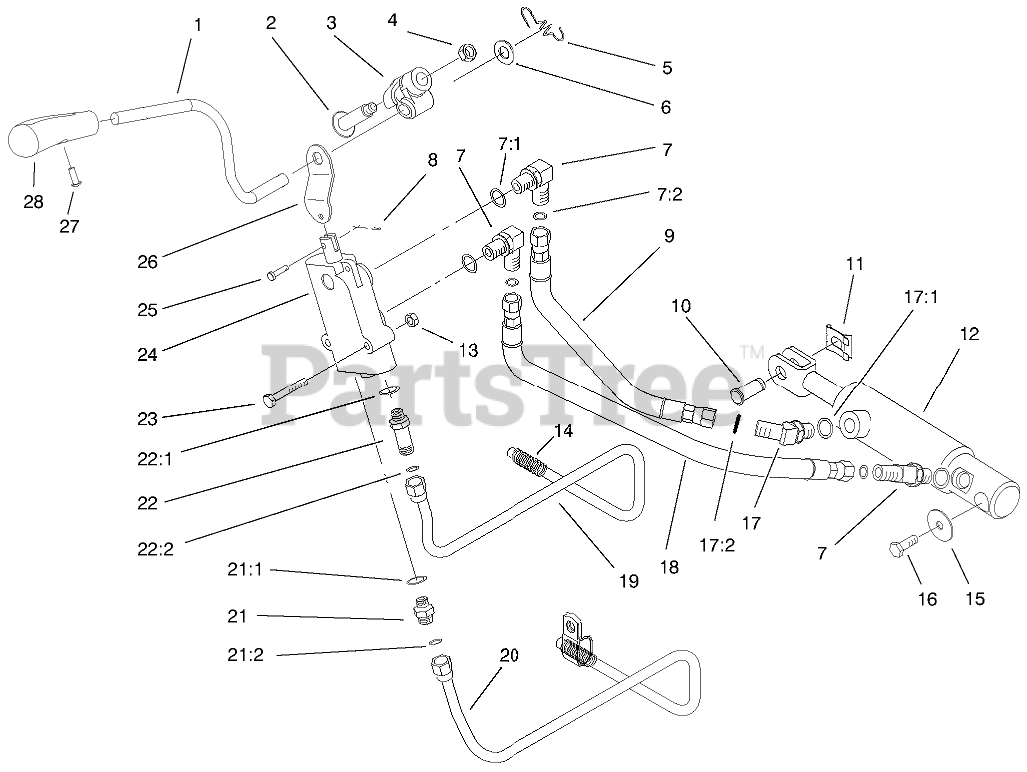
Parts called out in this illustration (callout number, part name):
1	HANDLE-LIFT
2	BOLT-SHOULDER
3	TRUNNION-LEVER, LIFT
4	NUT-JAM, LOCKING
5	SPRING-EXTENSION, LIFT
6	WASHER
7	FITTING-HYD, 90 DEGREE
7:1	O-RING
7:2	O-RING
8	PIN-COTTER
9	HOSE ASM
10	PIN-CLEVIS
11	CLIP-PIN
12	LIFT CYLINDER ASM
13	NUT-LOCK, NI
14	COVER-BRACE
15	WASHER-FLAT
16	SCREW-THREAD LOCKING
17	FITTING-HYD, 45 DEGREE
17:1	O-RING
17:2	O-RING
18	HOSE ASM
19	TUBE-HYD
20	TUBE - HYDRAULIC
21	FITTING-HYD. STRAIGHT
21:1	O-RING
21:2	O-RING
22	FITTING-HYD, LONG
22:1	O-RING
22:2	O-RING
23	SCREW-HH
24	VALVE - HYDRO LIFT
25	PIN-CLEVIS
26	LINK-LIFT
27	SCREW-PPHTF
28	Knob-Lift (Only On: 73470, 73540)
28	Knob-Lift (Only On: 73541)
